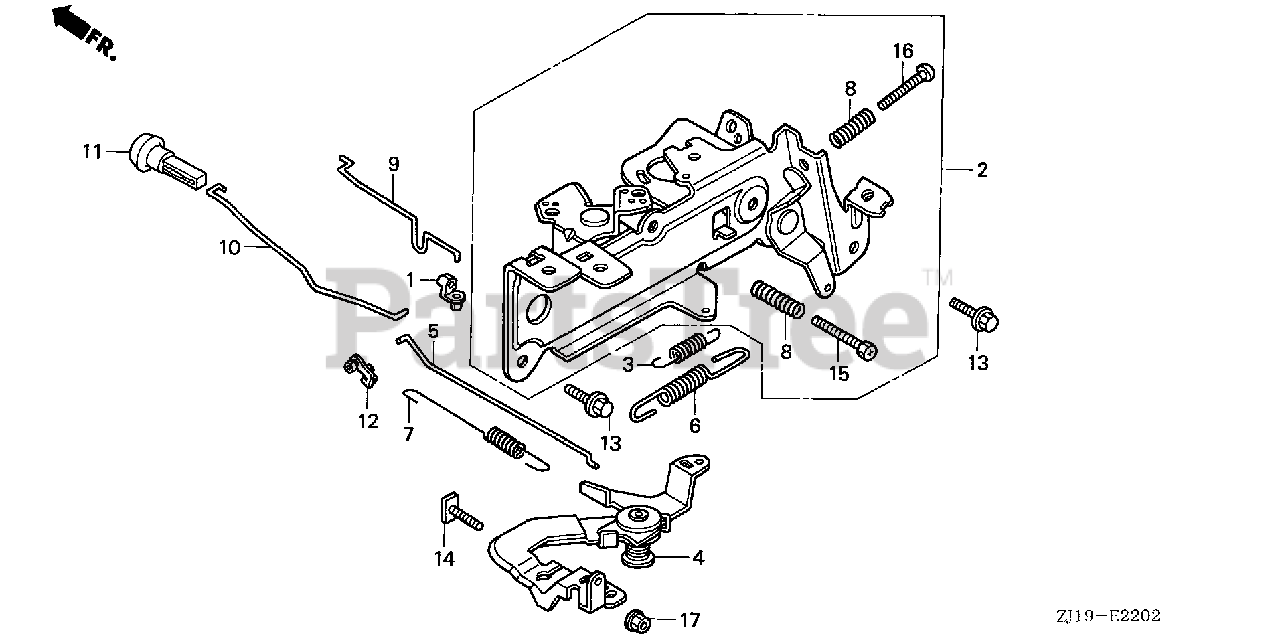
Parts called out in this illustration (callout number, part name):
1	JOINT, ROD
2	CONTROL ASSY. (AUTO THROTTLE)
3	SPRING, STARTER
4	ARM COMP., GOVERNOR
5	ROD, GOVERNOR
6	SPRING, GOVERNOR (MANUAL)
7	SPRING, THROTTLE RETURN
8	SPRING, CONTROL ADJUSTING
9	ROD, CHOKE CONTROL
10	ROD, CHOKE KNOB
11	KNOB, CHOKE
12	BUSH, LINKAGE
13	BOLT, FLANGE (6X14)
14	BOLT, GOVERNOR ARM
15	BOLT, SLOT (5X25)
16	SCREW, PAN (5X35)
17	NUT, FLANGE (6MM)
